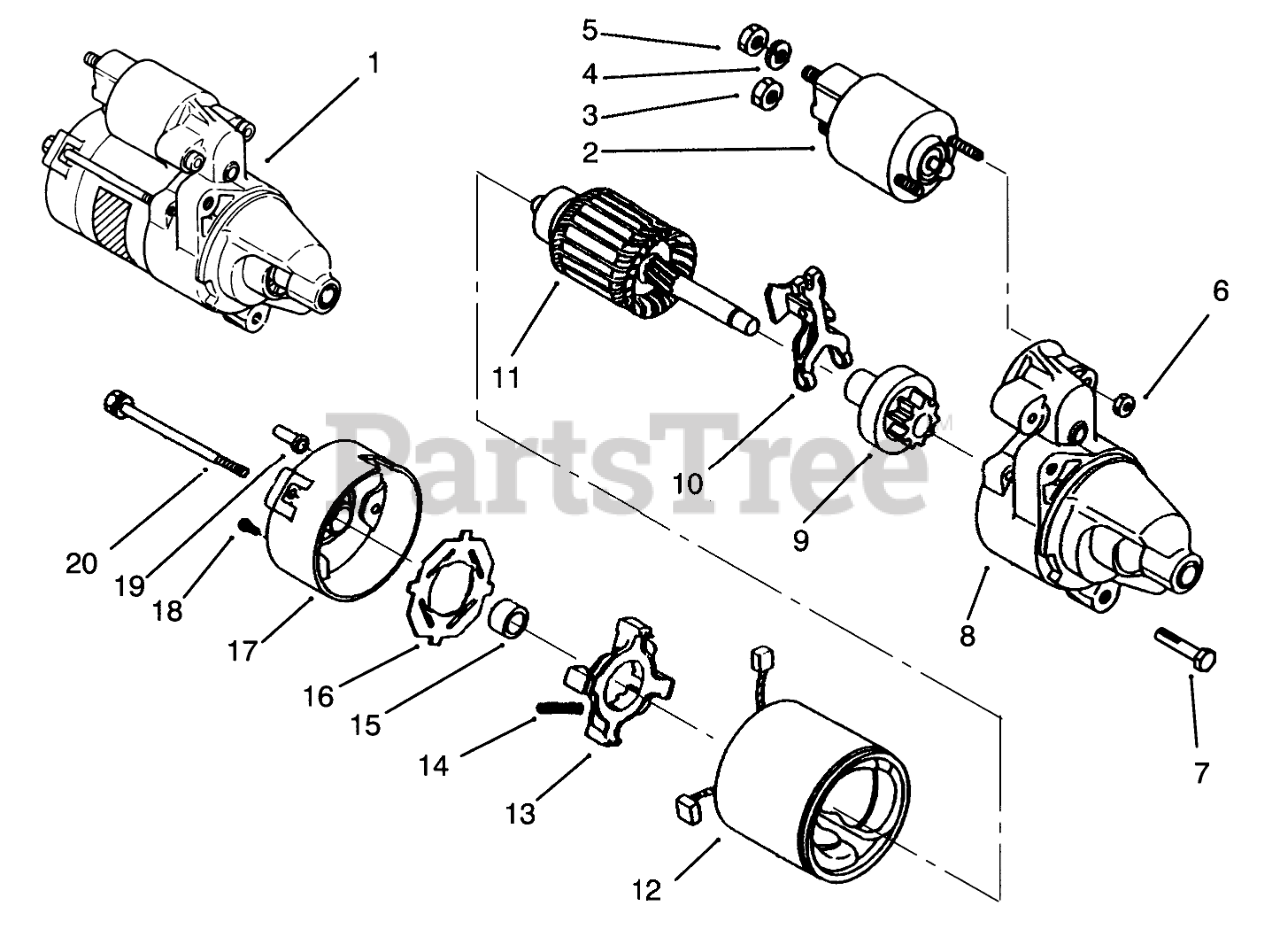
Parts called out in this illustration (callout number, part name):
1	STARTER
2	MAGNETIC SWITCH
4	SPRING WASHER
7	HEX HEAD CAPSCREW
8	Housing-Starter
9	Clutch
10	STARTER DRIVE LEVER
11	STARTER ARMATURE
12	STARTER FRAME
13	BRUSH HOLDER
14	BRUSH SPRING
15	OILLESS BEARING
16	INSULATOR
17	Frame-Commutator (Incl. Ref. #15-19)
19	COVER
20	THROUGH BOLT
